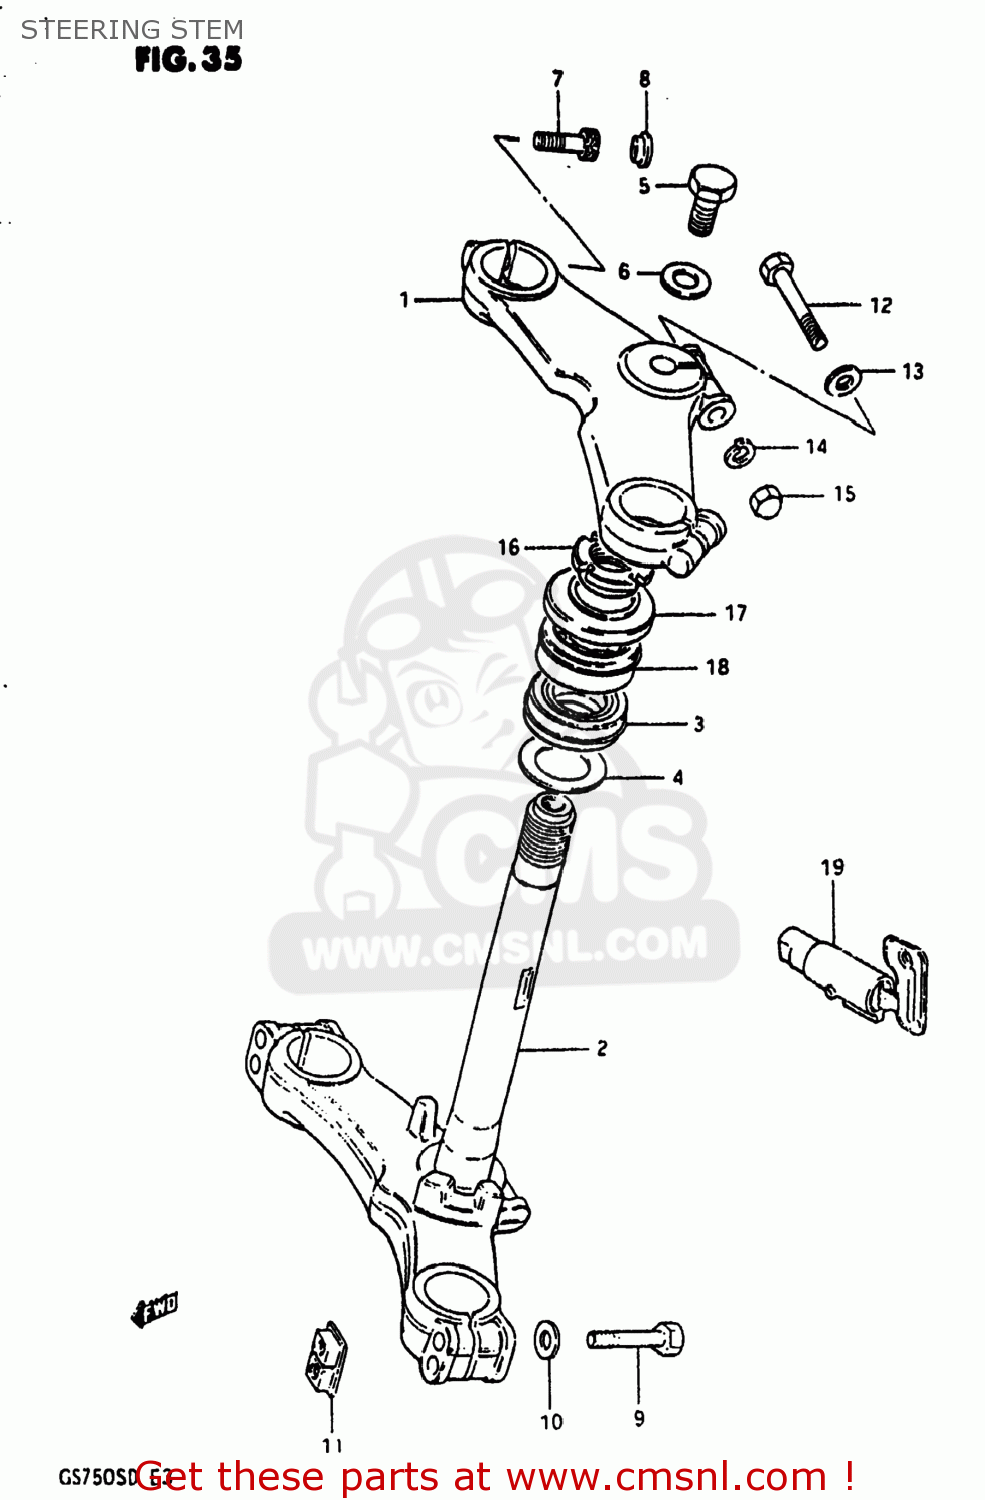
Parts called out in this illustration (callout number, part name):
1	HEAD,STEERING STEM
2	STEM,STEERING
3	BEARING
4	WASHER,THRUST
5	SUZUKI
6	SUZUKI
7	BOLT
8	CAP(OD:20)
9	BOLT 8X55
10	WASHER
11	NUT,FR FORK INNER TUBE
12	BOLT 8X50
13	WASHER
14	WASHER,LOCK,8.
15	NUT,M8X1.25X12
16	NUT,STEERING STEM
17	DUST SEAL,STEERING UPR
18	TAPER,ROLLER BEARING
19	LOCK ASSEMBLY,STEERING (NEI
